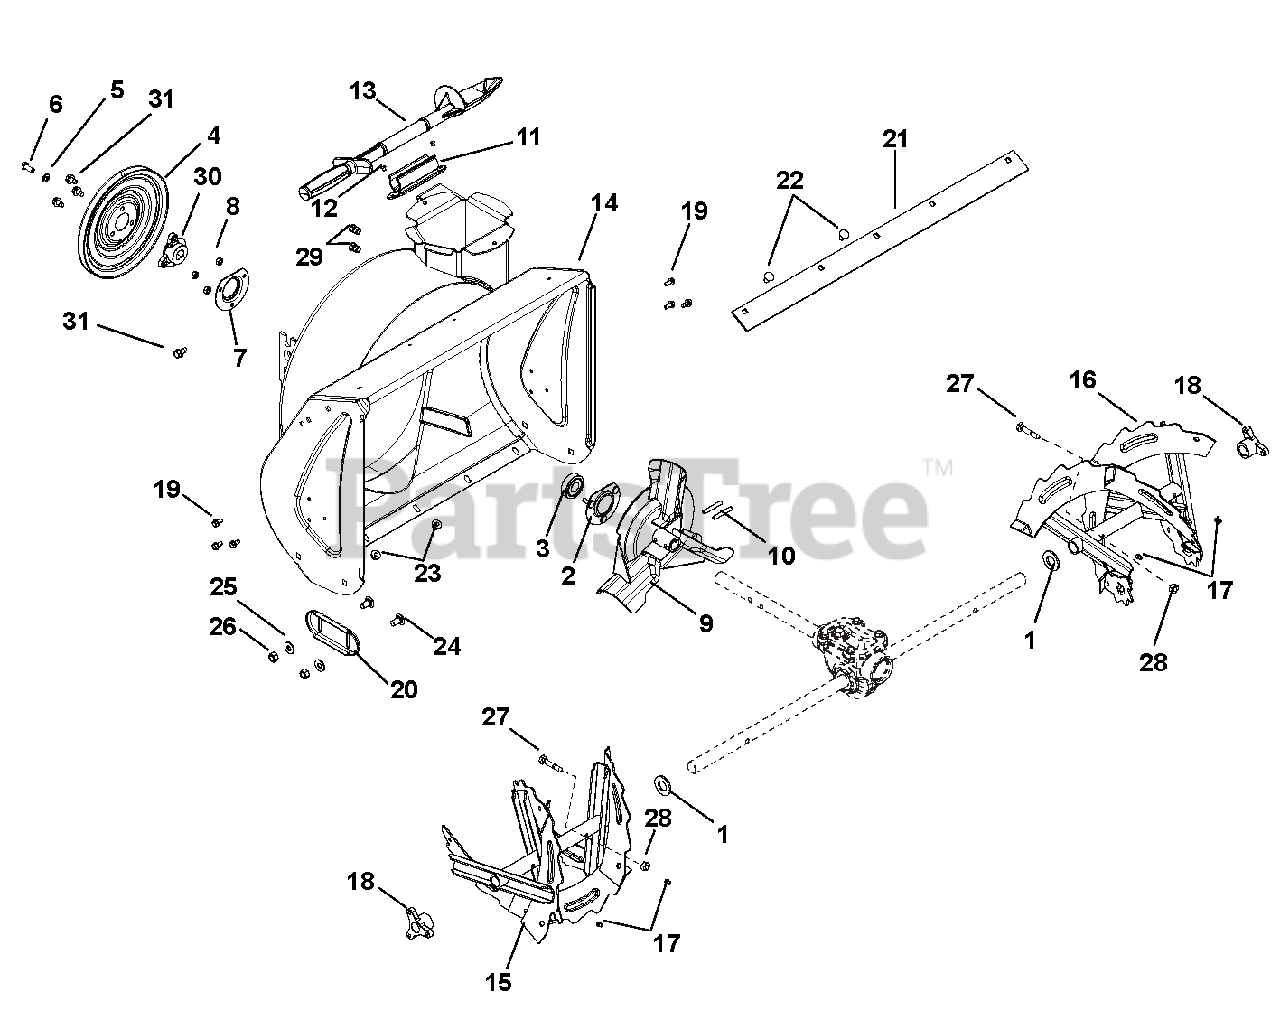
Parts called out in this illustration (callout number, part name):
1	@WSHR-FL-STL.812X1.50X.135YWZC
1	BSHG-SLV .75X1.12X1.062 NYL BK
2	BEARING FLANGE
3	BRG-BALL .750X1.750X.50
4	PULLEY,SPIN FORM SINGLE GROOVE
5	WSHR-LK .312X.097 HVY YWZC
6	BLT-HEX .31-24X.75 YWZC GR5
7	BEARING FLANGE
8	@NUT-LK-CTR .25-20 YWZC
9	IMPELLER, COMPACT 12" 3-BLADE
10	PIN-ROLL .250X1.75
11	MOUNT, SNOW CLEAN OUT
12	RVT-POP .187 YZ
13	DEVICE, SNOW CLEAN OUT
14	BLOWER HOUSING, 24"
14	BLOWER HOUSING, 28"
14	BLOWER HOUSING, 22"
15	RAKE, 24" RH, BLK SERR W/ZERK
15	RAKE, 28" RH, BLK SERR W/ZERK
15	AUGER, 20" RH, BLK SERR W/ZERK
16	RAKE, 24" LH, BLK SERR W/ZERK
16	RAKE, 28" LH, BLK SERR W/ZERK
16	AUGER, LH 20", BLK SERR W/ZERK
17	ZERK,FITTING .25X.125 DRIVE IN
18	BUSHING, RAKE SHAFT .75"
19	SCR-TAP .25-20X.50 HWH TR YWZ
20	SKID SHOE, REVERSIBLE
21	SCRAPER BLADE, 28" COMPACT HI
21	SCRAPER BLADE, 24" COMPACT HI
21	SCRAPER BLADE, 22" COMPACT HI
22	BOLT, MODIFIED HEAD CARRIAGE
23	@NUT-LK-TOP-FLG .31-18 YWZC
24	@BLT-RHDSSQNK .38-16X.75 G5YZ
25	@WSHR-FL-STL.38X.875X.083 YWZC
26	@NUT-LK-CTR .38-16 YWZC
27	SHEAR BOLT WITH NUT
28	@NUT-LK-CTR .25-20 YWZC
29	NUT, THREADED INSERT .38-16
30	PULLEY HUB, BOLT-ON D-BORE .75
31	@SCR-TAP .31-18X.50 HWH TR YWZ
